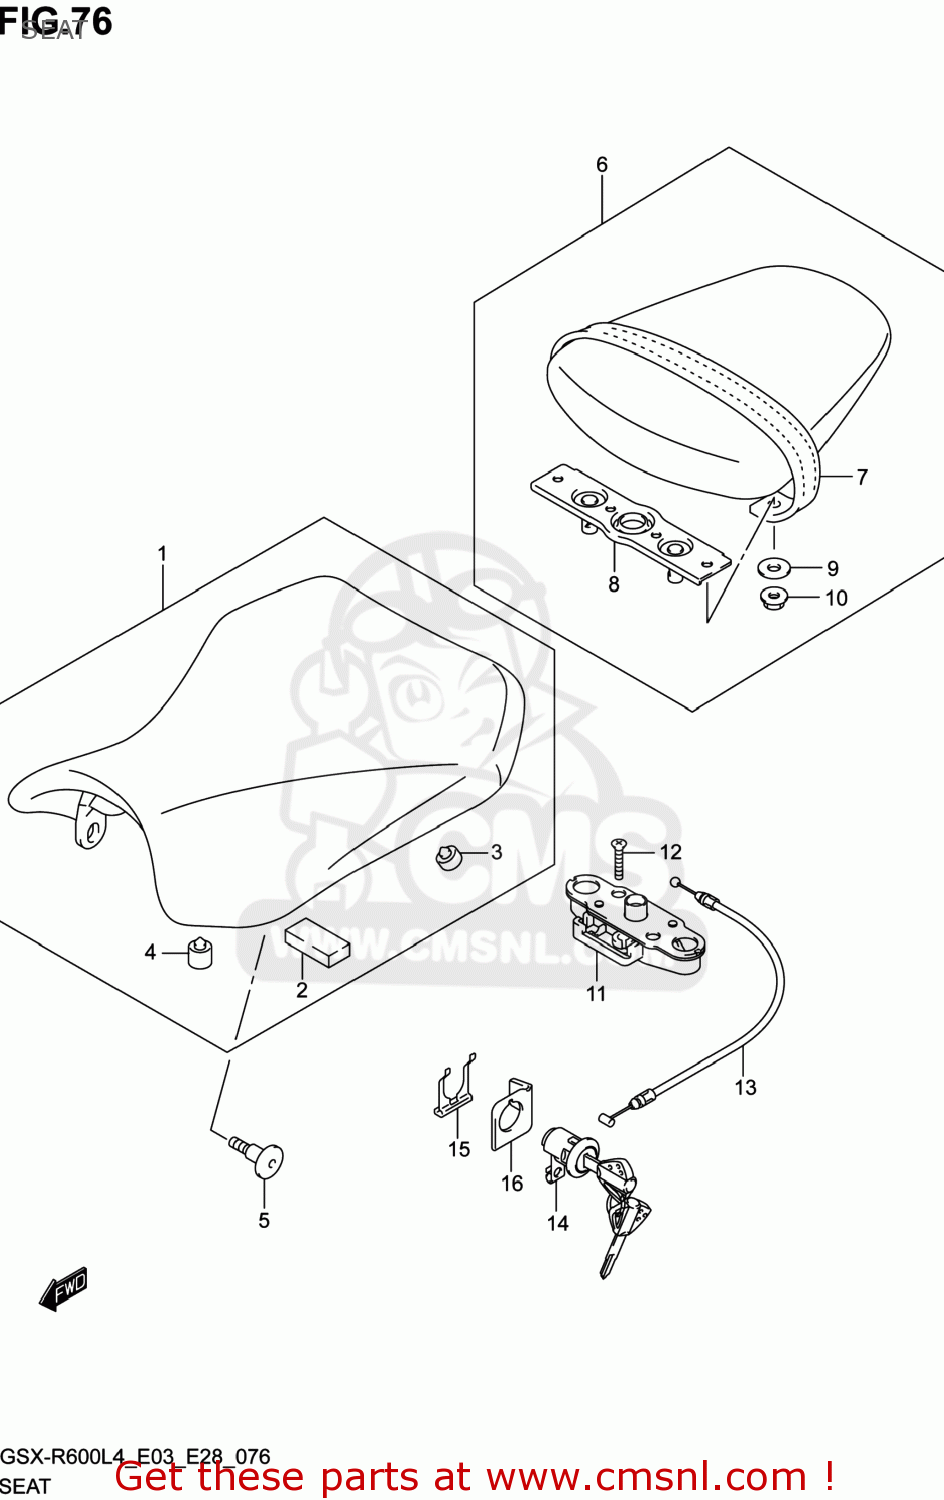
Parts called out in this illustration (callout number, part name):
1	SEAT ASSY
2	CUSHION
3	CUSHION
4	CUSHION
5	SCREW(6X20)
6	SEAT ASSY,PILLION
7	BAND ASSY,SEAT
8	STRIKER
9	WASHER(6.5X20X1.6)
10	NUT
11	BRACKET,SEAT SUPPORT
12	SCREW
13	CABLE,SEAT LOCK
14	LOCK SET,SEAT
15	PLATE,SEAT LOCK ASSY
16	GUIDE,SEAT LOCK CABLE
